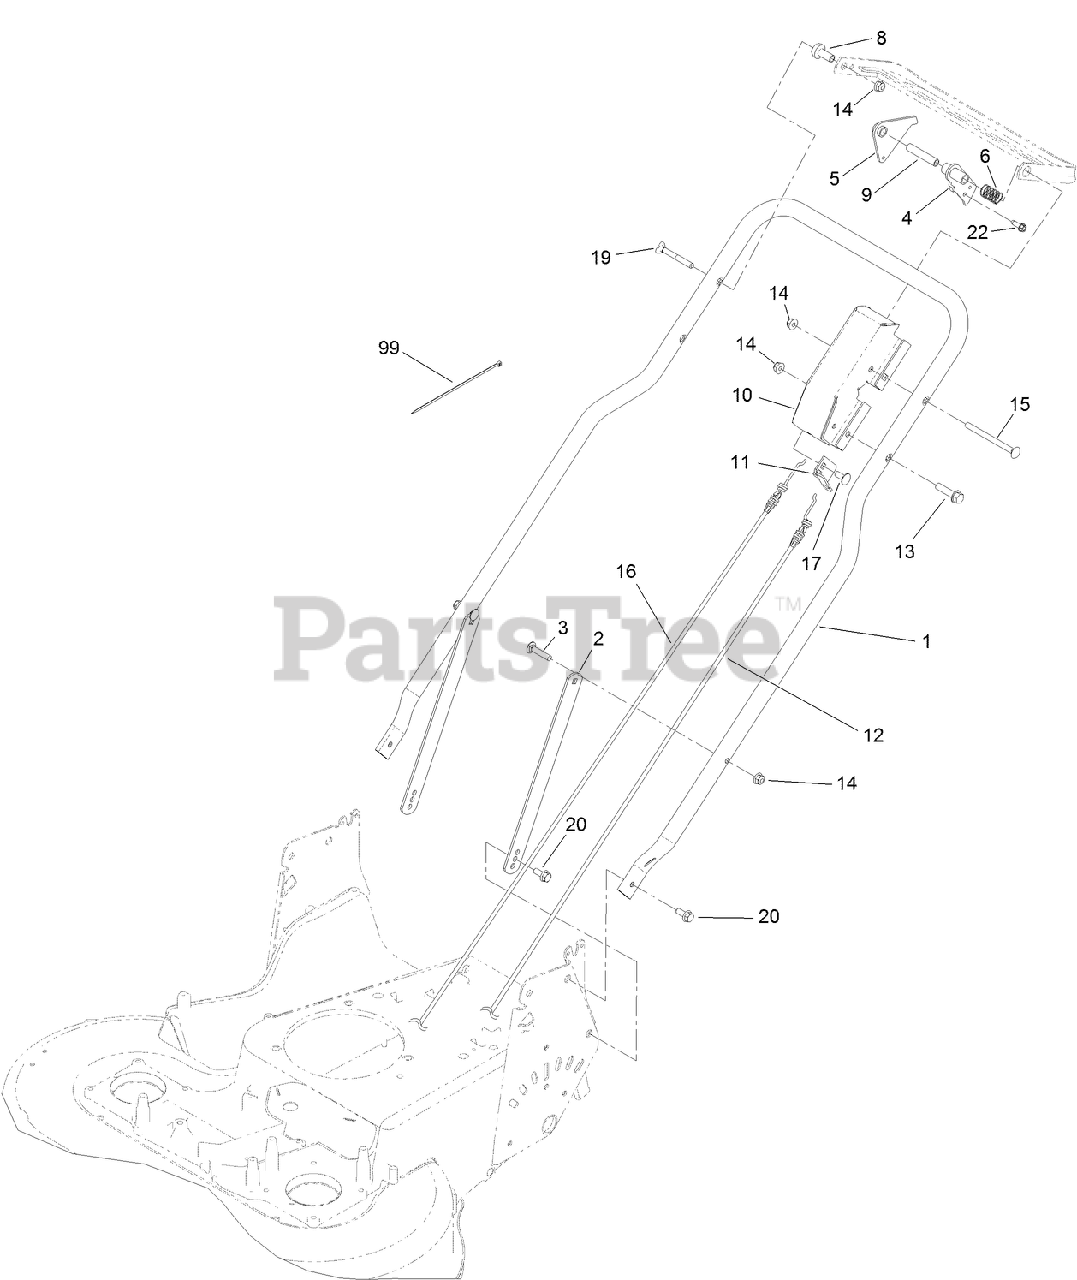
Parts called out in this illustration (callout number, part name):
2	SUPPORT-HANDLE
3	BOLT-CARR
4	BBC LEVER ASM
5	LEVER-TRACTION
6	SPRING-CONTROL
8	SPACER-SUPPORT
9	SPACER-BRACKET, CONTROL
10	BRACKET-CONTROL
11	BRACKET
12	CABLE-BRAKE
13	SCREW-HWH
14	NUT-HF, NI
15	SCREW-CARR
16	CABLE-TRACTION
17	SCREW-CARR
19	SCREW
20	SCREW-HHF
22	SCREW-HWHTF
99	TIE-CABLE
